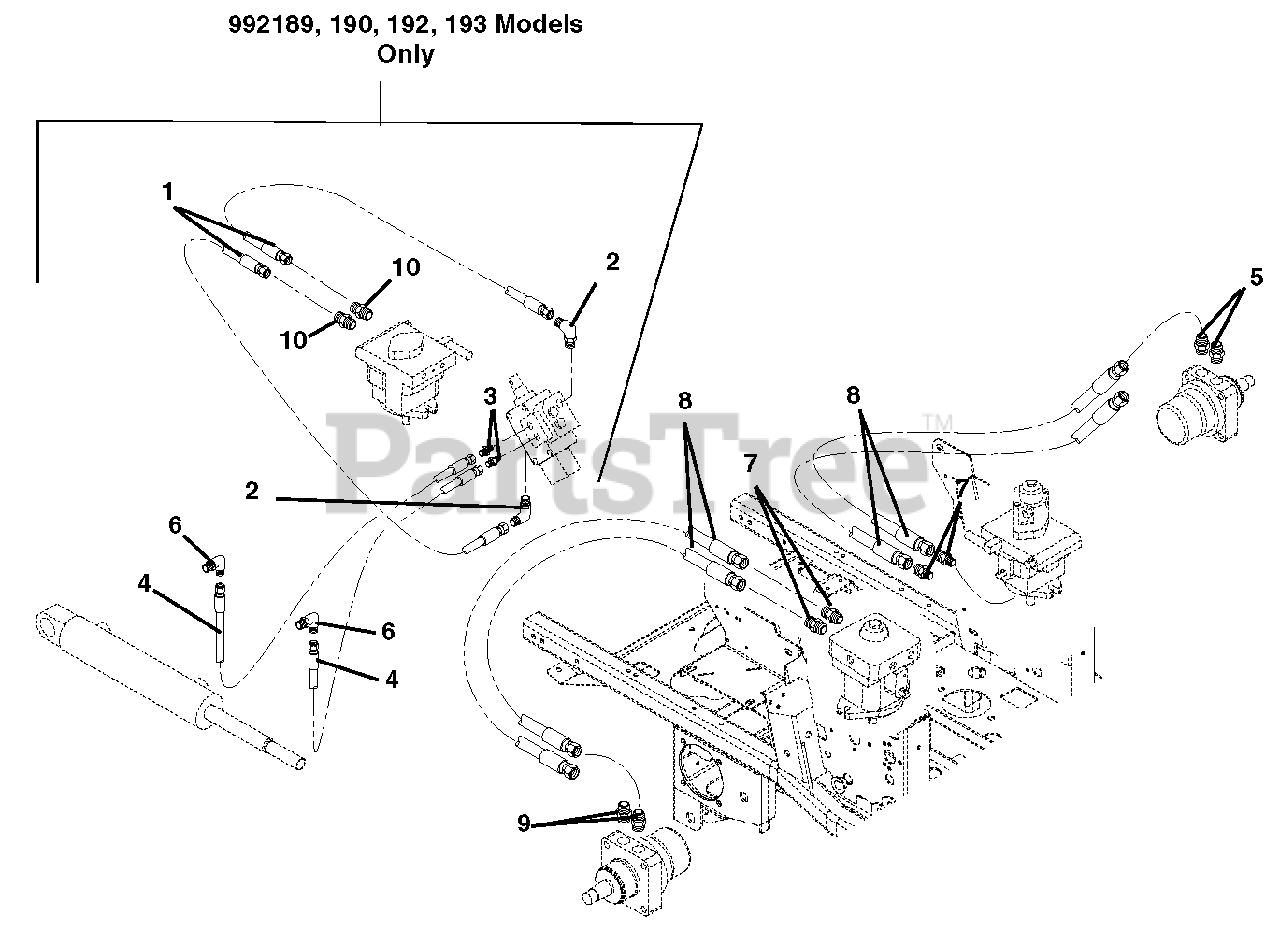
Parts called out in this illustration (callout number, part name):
1	Hose, Hydraulic (992189, 190, 192, 193)
2	Hydraulic, Fitting Elbow (992189, 190, 192, 193)
3	Adapter (4-6F5OLO) (992992189, 190, 192, 193)
4	Hose, Hydraulic (992189, 190, 192, 193)
5	Fitting, Hyraulic Straight (8-10 F5OLO-S)
6	Fitting, Hydraulic (4 C5OLO) (992189, 190, 192, 193)
7	Adapter, Face Seal 8 x 8 .50 O-Ring
8	Hose, Hydraulic .50
9	Adapter, Hydraulic Steel (M10 O-M8F)
10	Fitting, Hydraulic (4 F5OLO) (Supplied with pump) (992189, 190, 192, 193)
